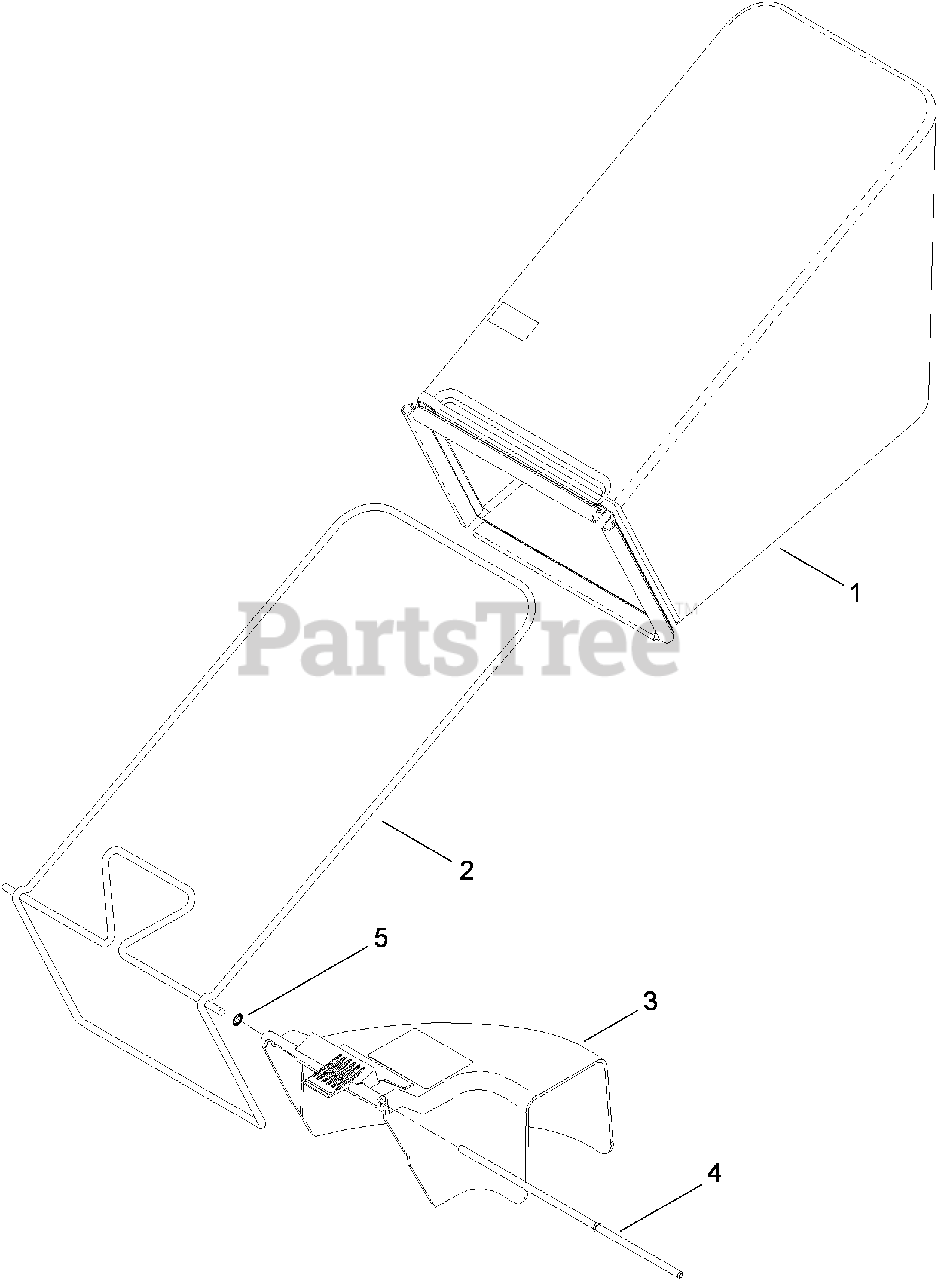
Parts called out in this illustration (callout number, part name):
1	GRASS BAG ASM
2	FRAME-BAG
3	REAR DEFLECTOR ASM
5	RING-RETAINING
